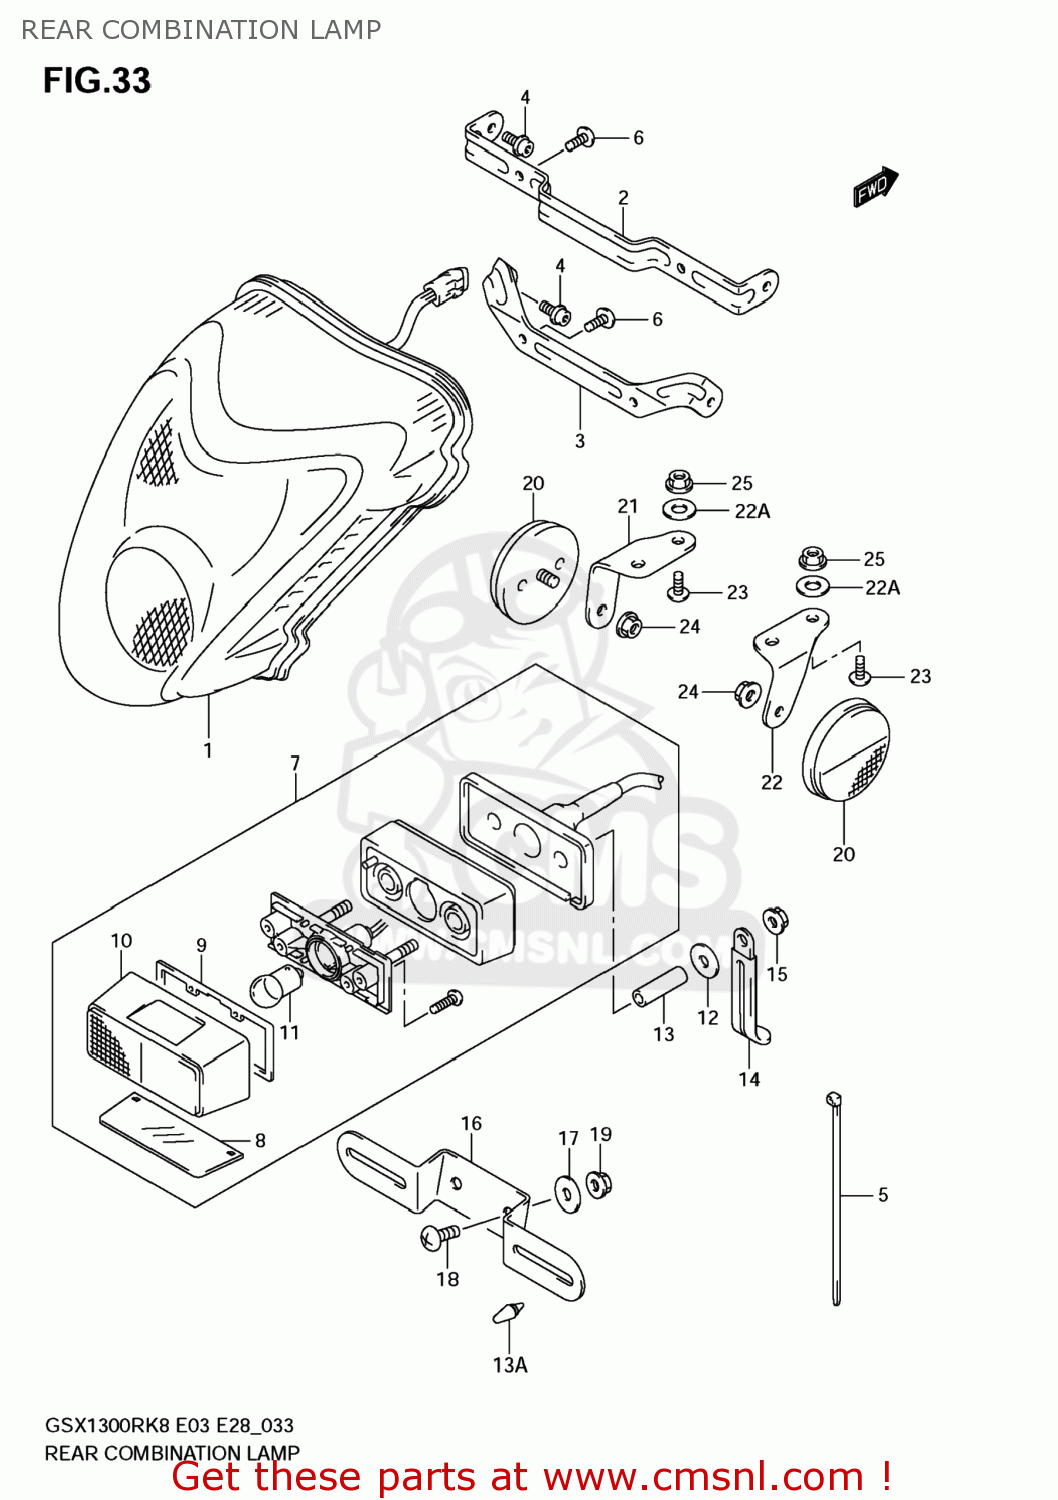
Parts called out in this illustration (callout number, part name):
1	LAMP ASSY,RR COMBINATION
2	BRACKET,RR COMBINATION LAMP
3	BRACKET,RR COMBINATION LAMP
4	BOLT(5X12)
5	CLAMP(L:145)
6	SCREW
7	LAMP ASSY,LICE
8	LENS LICENCE
9	GASKET (NAS)
10	COVER,LICENSE LAMP
11	BULB(12V5W,BF150-40160A)
12	WASHER(6.5X20X1.2)
13	SPACER(6.5X9X34)
13A	CUSHION
14	CLAMP(L:45)
15	NUT
16	BRACKET,LICENSE PLATE
17	WASHER(6.5X20X1.2)
18	SCREW
19	NUT
20	REFLECTOR ASSY,RR SIDE
21	BRACKET,RR SIDE RR,R
22	BRACKET,RR SIDE RR,L
22A	WASHER(6.5X14X2)
23	SCREW
24	NUT
25	NUT
